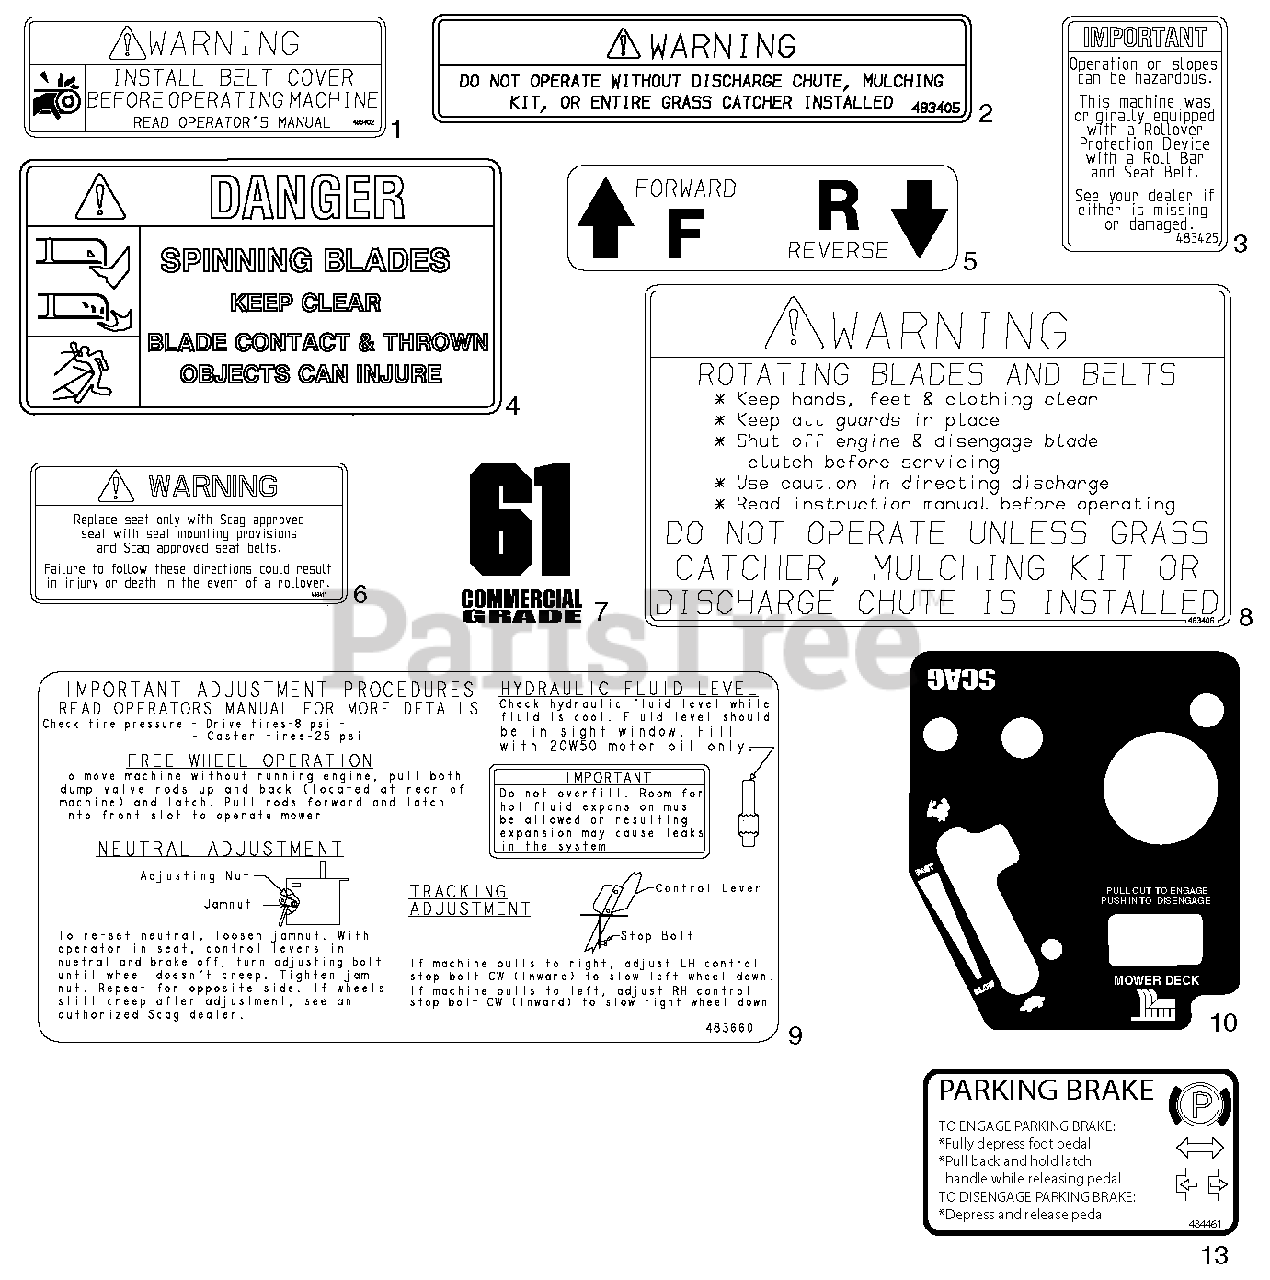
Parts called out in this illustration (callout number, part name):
1	Decal, Belt Cover
2	Decal, Warning
3	Decal, ROPS
4	Decal, Spinning Blades
5	Decal, Traction Control
6	Decal, Seat Replacement
7	Decal, 52 Commercial
7	Decal, 61 Commercial
8	Decal, Knives
9	Decal, Adjustment SFZ
10	Decal, Instrument Panel
11	Decal, Front SFZ Pro
12	Decal, Cutting Height - SFZ Pro
13	Decal, Brake
14	Decal, SFZ Replacement Parts
